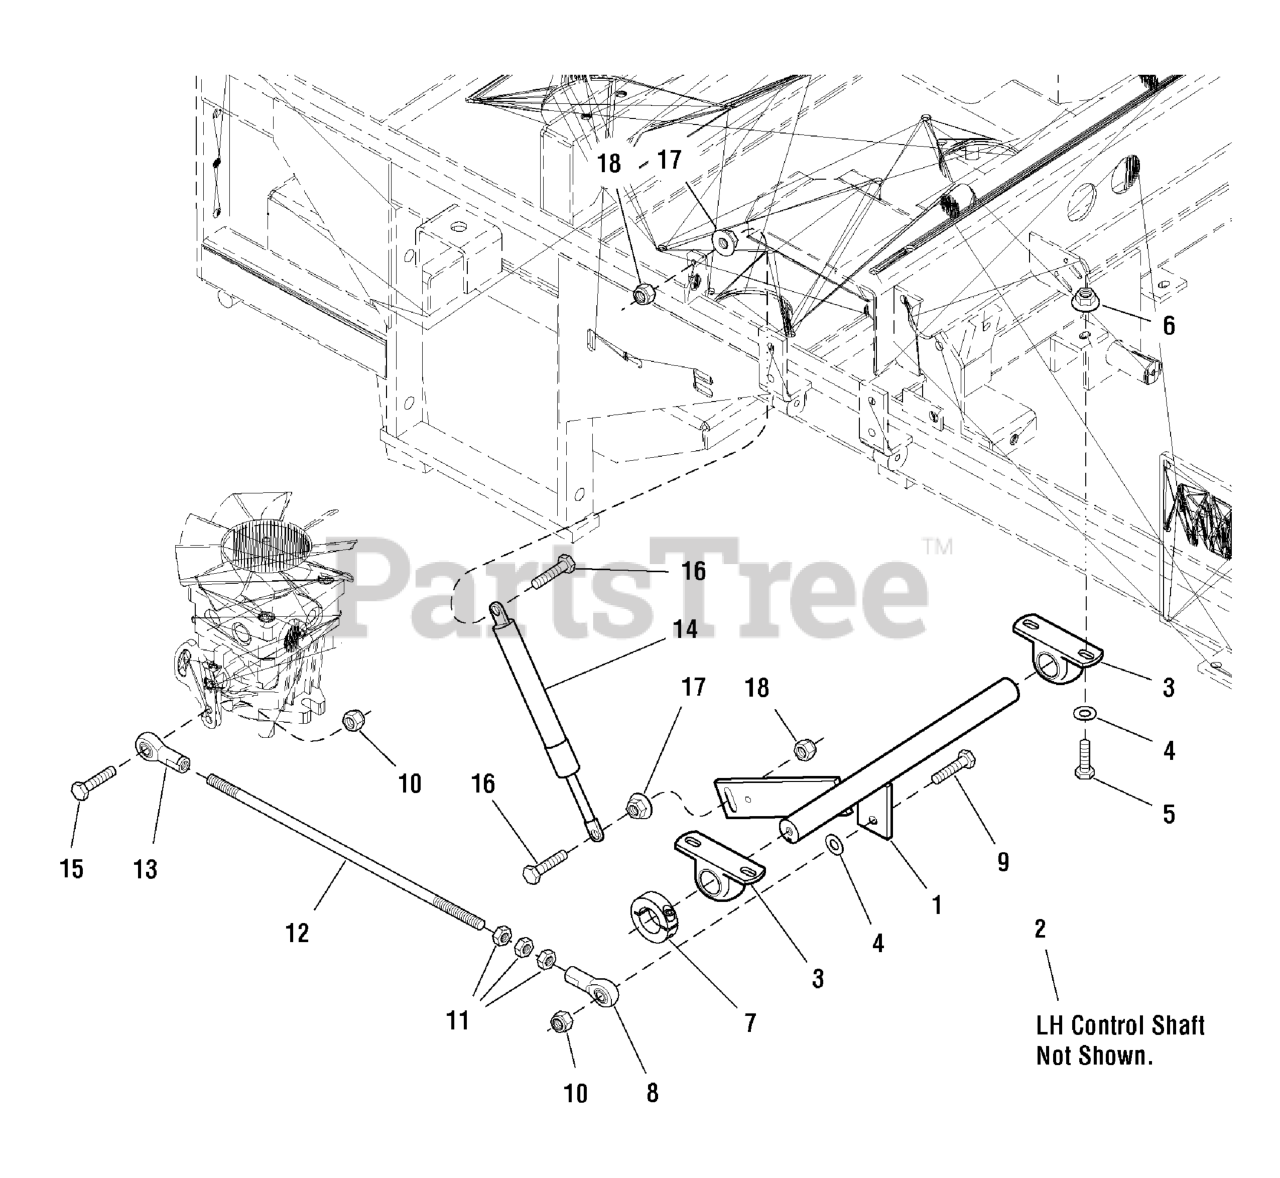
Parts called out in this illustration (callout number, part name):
1	CONTROL SHAFT-RH
3	BEARING, Pillow Block
4	WASHER, 5/16" SAE
5	BOLT, 5/16-18 X 1 GD5 YZ
6	NUT, 5/16-18 HEX SERRATED FLANGE (SMALL)
7	COLLAR, 1" Split
8	BALL JOINT 5/16-24 RH FEMALE BRONZE RACE
9	BOLT, 5/16-18 x 1-1/4
10	NUT, 5/16-18 Hex Nylon Lock
11	NUT, 5/16-24 Hex
12	HYDRO LINKAGE ROD
13	BALL JOINT 5/16-24 LH FEMALE BRONZE RACE
14	DAMPENER
15	BOLT, 5/16-18 x 1-1/8
16	BOLT, M8 x 35MM
17	NUT, M8-1.25 Hex Serrated Flange
18	NUT, M8-1.25 Hex Nylon Lock
